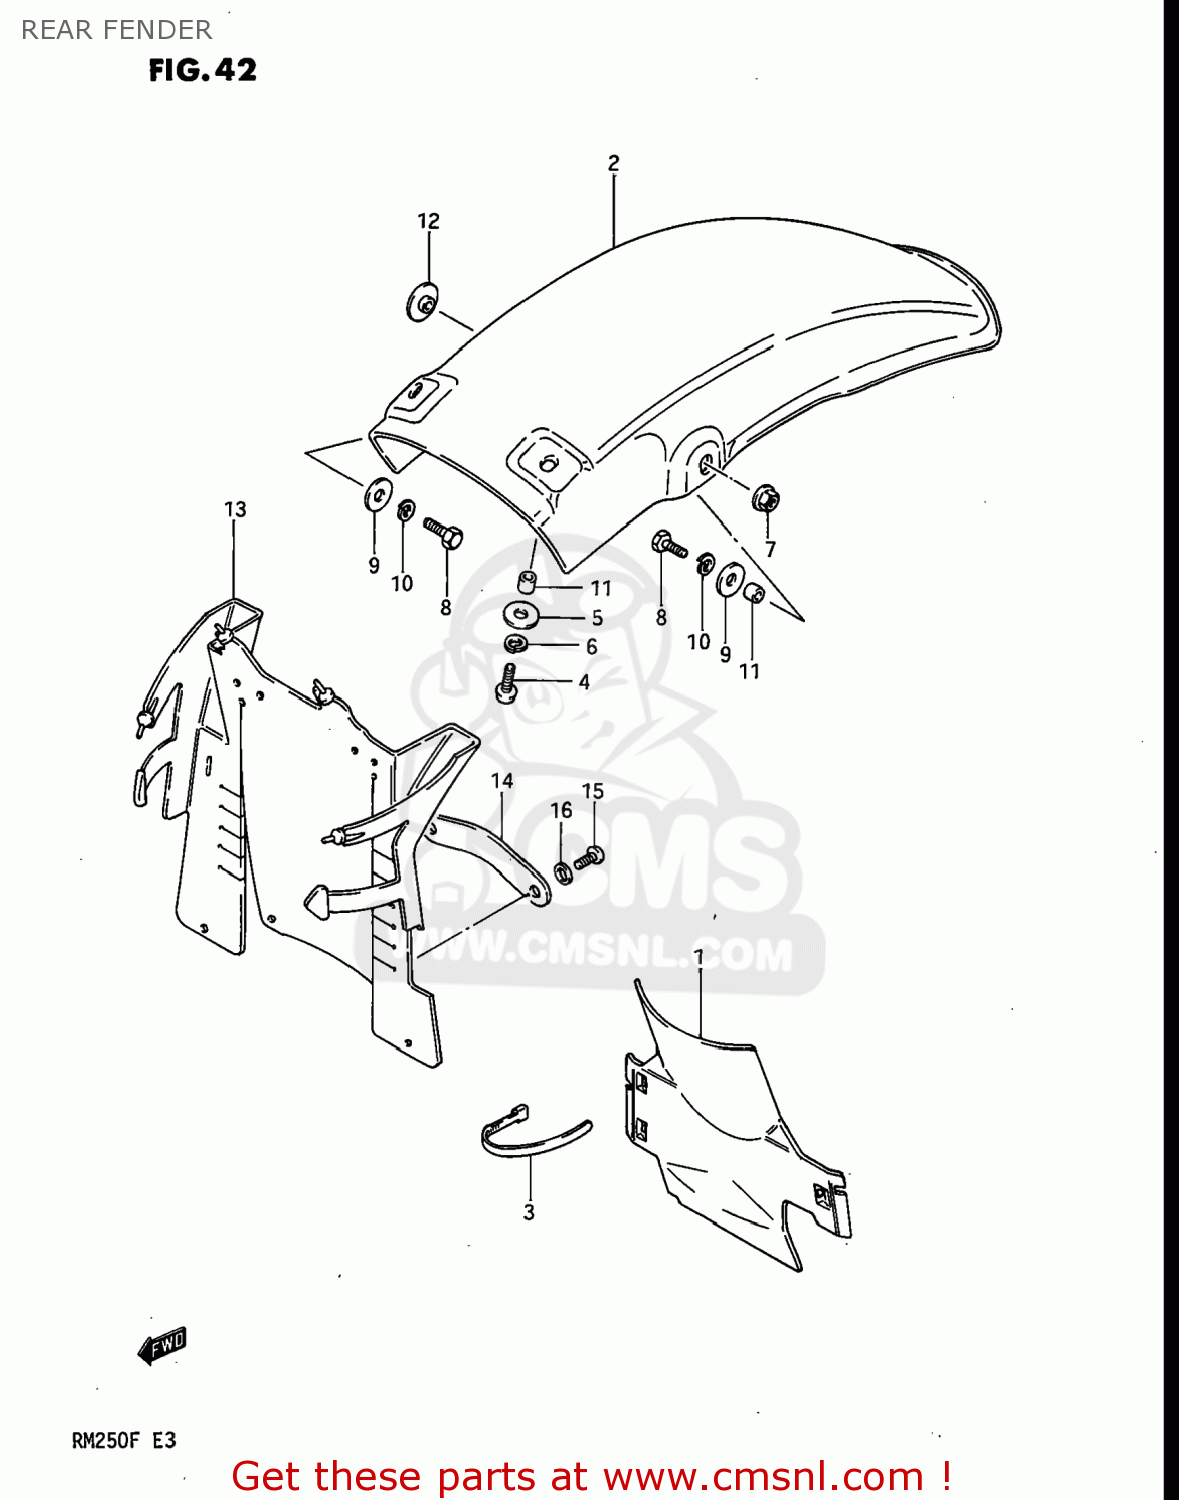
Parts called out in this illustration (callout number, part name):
1	FENDER,FRONT,REAR
2	FENDER,REAR
3	CLAMP
4	SCREW
5	WASHER
6	LOCK WASHER
7	NUT
8	BOLT
9	WASHER (6.5X20X1.2)
10	LOCK WASHER
11	SPACER
12	WASHER
13	GUARD,REAR FENDER MUD
14	PLATE,MUD GUARD
15	SCREW
16	WASHER,5MM
